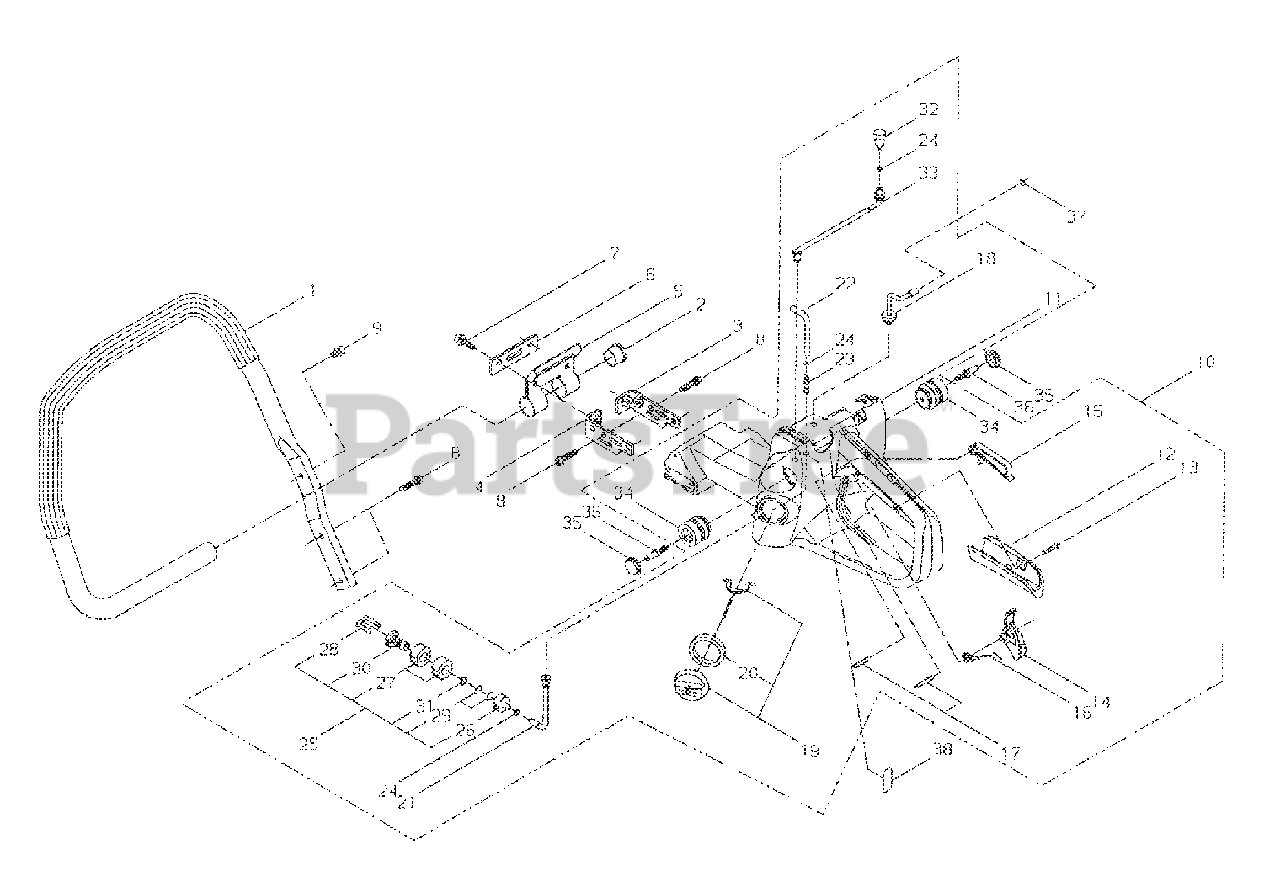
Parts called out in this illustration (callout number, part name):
1	HANDLE, FRONT
2	CAP
3	STAY - RIGHT
4	STAY - LEFT
5	BRACKET
6	PLATE
7	BOLT
8	BOLT
9	BOLT
10	REAR HANDLE ASSY
11	HANDLE, REAR
12	GRIP, LOWER
13	SCREW - TAPPING
14	TRIGGER, THROTTLE
15	LOCKOUT, TRIGGER
16	SPRING, THROTTLE RETURN
17	PIN 4×25
18	TUBE
19	CAP ASSY
20	GASKET, CAP
21	TUBE
22	TUBE
23	CONNECTOR, PIPE
24	CLIP Ø6
25	FUEL FILTER ASSY
26	WEIGHT, FUEL LINE
27	FILTER
28	CLIP, FILTER
29	SCREEN, FILTER
30	BODY, FUEL FILTER
31	RING, RETAINING
32	VALVE
33	TUBE
34	CUSHION 5
35	CAP, CUSHION
36	BOLT, STOPPER LIMITER
37	CLIP Ø6
38	LABEL - INSTRUCTION
